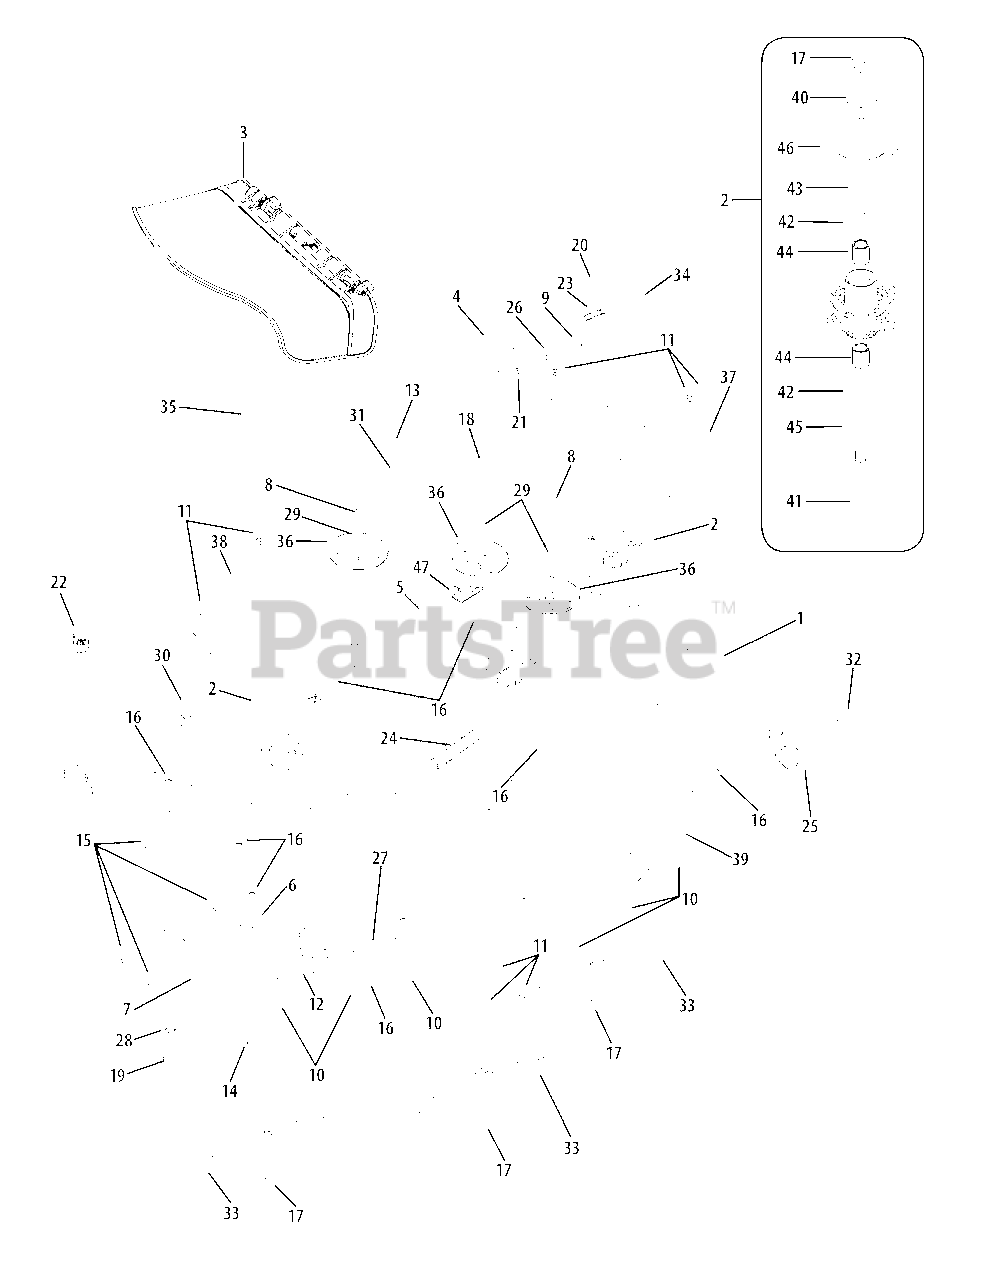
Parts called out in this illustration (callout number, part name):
1	Deck Housing
2	Spindle Assembly w/pulley
3	Discharge Chute Assembly
4	Deck Hanger Bracket
5	Idler Arm
6	Stop Bracket
7	Finger Guard
8	Hex Cap Screw, 3/8-16 x 1.75
9	Hex Cap Screw, 5/16-18 x 1.25
10	Hex Washer Head Screw, 1/4-20 x .5
11	Hex Washer Head Screw, 5/16-18 x .750
12	RH Skirt
13	Hex Cap Screw, 3/8-16 x 1.25
14	Hex Screw, 3/8-16 x 1.00
15	Carriage Screw, 3/8-16 x .75
16	Hex Insert Flange Lock Nut, 3/8-16
17	Hex Flange Nut, 5/8-18
18	Hex Cap Screw, 3/8-16 x 2.00
19	Hex Nut, M16-1.5
20	Cotter Pin, 1/8 x 1.25
21	Deck Adjustment Gear
22	Water Nozzle Adapter
23	Compression Spring, .535 x 1.751
24	Extension Spring, .94 x 6.74
25	Deck Ball Wheel, 5.0
26	Lock Washer, 5/16
27	Bell Washer, .45 x 1.0 x .062
28	Internal Tooth Lock Washer, 5/8
29	Flat Washer, .38 x .93 x .110
30	Deck Wash Nozzle
31	Shoulder Spacer, .884 x .190
32	Shoulder Screw, .5 x 2.5 x 3/8-16
33	Blade, 2 in 1, 17.9"
34	Deck Hanger Rod
35	V-Belt Type A Sec x 134
36	Idler Pulley, 4.25 Dia
37	Belt Cover, LH
38	Belt Cover, RH
39	Center Skirt
40	Flat Washer, .76 x 1.50 x .12
41	Spindle Shaft, 5.75
42	Ball Bearing
43	Spacer, .79 x 1.25 x .175
44	Spacer, .80 x 1.10 x 1.32
45	Spacer, .79 x 1.82 x .55
46	V-Type Pulley, 5.39
47	Bracket, Belt Guard
